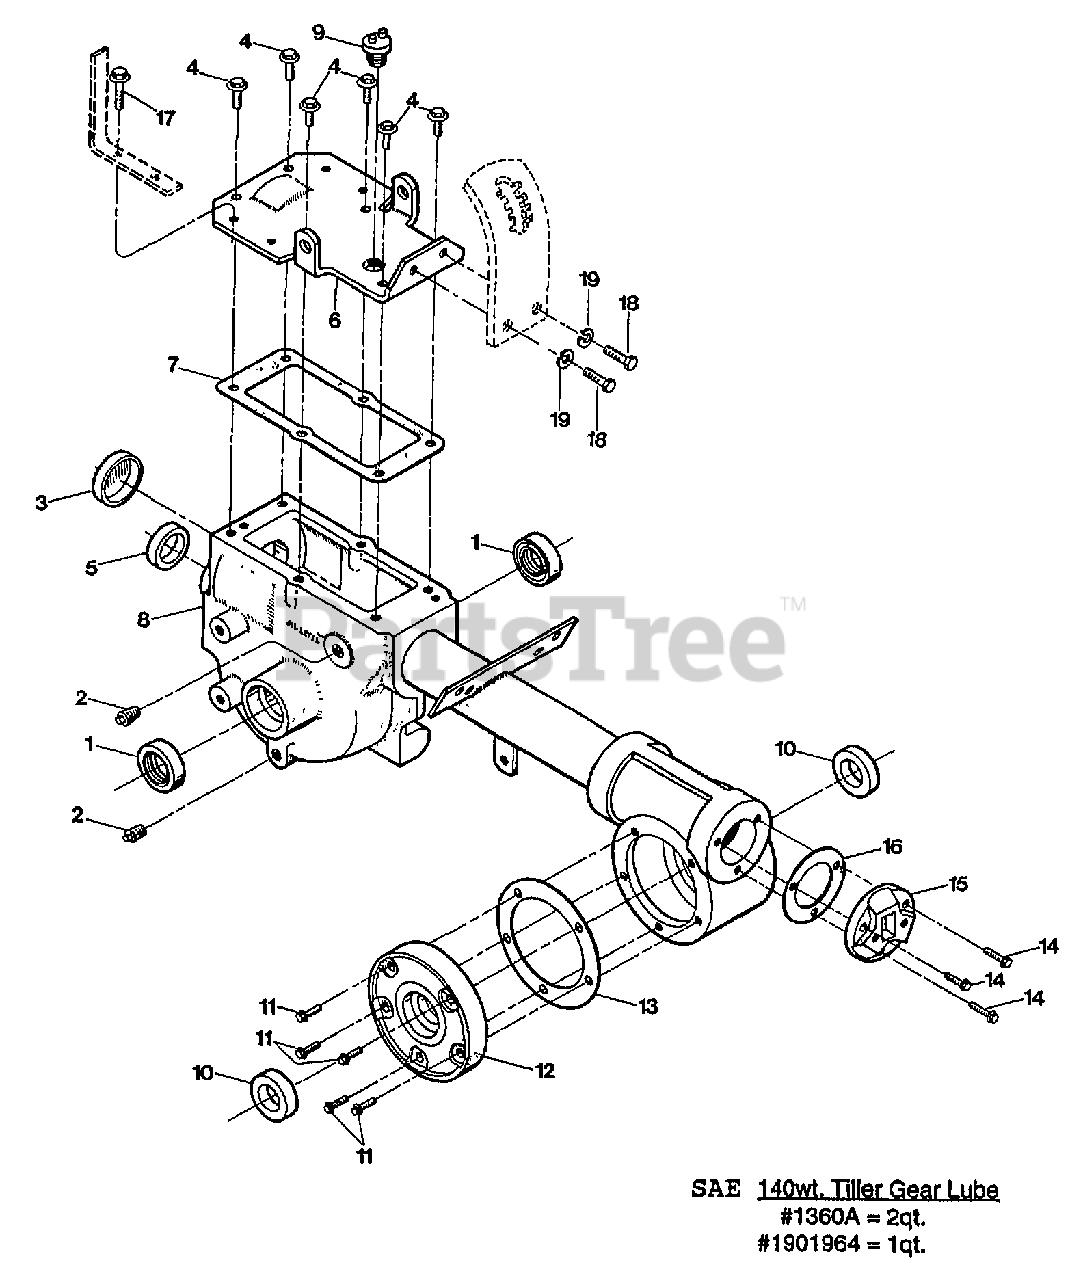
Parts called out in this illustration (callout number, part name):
1	SEAL-OIL WHEELSHAFT
2	PLUG-PIPE 1/4 NPT
3	SEAL-BORE
4	SCR-HFLK 5/16-18X.75 ZP
5	SEAL-PINION SHAFT PT/85030/00
6	KIT-COVER TRANS W/HDW
7	GASKET-TRANS COVER
8	ASSM-TRANS A-UNIT JR W/UP
9	PLUG-OIL FILL 3/4-10
10	SEAL-TILLER SHAFT
11	SCR-HXSKT 1/4-20X.625
12	COVER-TILLER HSG MACH
13	GASKET-TILLER COVER (FITS ALL COVERS)
14	SCR-HFLK 1/4-20X.87
15	CAP-REAR #1115
16	GASKET-BRG COVER
17	SCR-HFLK 5/16-18X1.00 ZP
18	SCR-HH 3/8-16X.75 G5 ZP
19	WASHER-LK .375 @ DEPL
